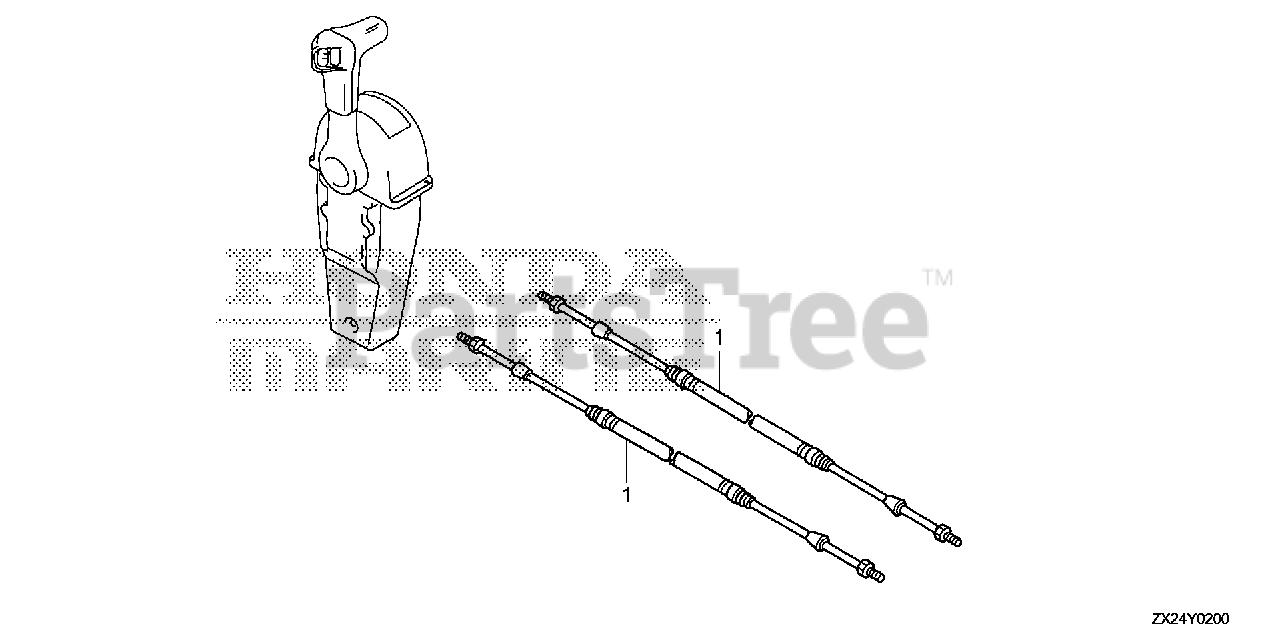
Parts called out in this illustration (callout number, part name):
1	CABLE, REMOTE CONTROL (10') (LOW FRICTION)
1	CABLE ASSY., PUSH-PULL (33C-5FT)
1	CABLE, REMOTE CONTROL (11') (LOW FRICTION)
1	CABLE ASSY., PUSH-PULL (33C-6FT)
1	CABLE, REMOTE CONTROL (12') (LOW FRICTION)
1	CABLE ASSY., PUSH-PULL (33C-7FT)
1	CABLE, REMOTE CONTROL (13') (LOW FRICTION)
1	CABLE ASSY., PUSH-PULL (33C-8FT)
1	CABLE, REMOTE CONTROL (14') (LOW FRICTION)
1	CABLE ASSY., PUSH-PULL (33C-9FT)
1	CABLE, REMOTE CONTROL (15') (LOW FRICTION)
1	CABLE ASSY., PUSH-PULL (33C-10FT)
1	CABLE, REMOTE CONTROL (16') (LOW FRICTION) (NOT AVAILABLE)
1	CABLE ASSY., PUSH-PULL (33C-11FT)
1	CABLE, REMOTE CONTROL (17') (LOW FRICTION)
1	CABLE ASSY., PUSH-PULL (33C-12FT)
1	CABLE, REMOTE CONTROL (18') (LOW FRICTION) (NOT AVAILABLE)
1	CABLE ASSY., PUSH-PULL (33C-13FT)
1	CABLE, REMOTE CONTROL (19') (LOW FRICTION)
1	CABLE ASSY., PUSH-PULL (33C-14FT)
1	CABLE, REMOTE CONTROL (20') (LOW FRICTION) (NOT AVAILABLE)
1	CABLE ASSY., PUSH-PULL (33C-15FT)
1	CABLE, REMOTE CONTROL (21') (LOW FRICTION)
1	CABLE ASSY., PUSH-PULL (33C-16FT)
1	CABLE, REMOTE CONTROL (22') (LOW FRICTION) (NOT AVAILABLE)
1	CABLE ASSY., PUSH-PULL (33C-17FT)
1	CABLE, REMOTE CONTROL (23') (LOW FRICTION)
1	CABLE ASSY., PUSH-PULL (33C-18FT)
1	CABLE, REMOTE CONTROL (24') (LOW FRICTION) (NOT AVAILABLE)
1	CABLE ASSY., PUSH-PULL (33C-19FT)
1	CABLE, REMOTE CONTROL (25') (LOW FRICTION)
1	CABLE ASSY., PUSH-PULL (33C-20FT)
1	CABLE, REMOTE CONTROL (26') (LOW FRICTION)
1	CABLE ASSY., PUSH-PULL (33C-21FT)
1	CABLE, REMOTE CONTROL (27') (LOW FRICTION)
1	CABLE ASSY., PUSH-PULL (33C-22FT)
1	CABLE, REMOTE CONTROL (28') (LOW FRICTION) (NOT AVAILABLE)
1	CABLE ASSY., PUSH-PULL (33C-23FT)
1	CABLE, REMOTE CONTROL (29') (LOW FRICTION)
1	CABLE ASSY., PUSH-PULL (33C-24FT)
1	CABLE, REMOTE CONTROL (30') (LOW FRICTION) (NOT AVAILABLE)
1	CABLE ASSY., PUSH-PULL (33C-25FT)
1	CABLE, REMOTE CONTROL (31') (LOW FRICTION)
1	CABLE ASSY., PUSH-PULL (33C-26FT)
1	CABLE, REMOTE CONTROL (32') (LOW FRICTION) (NOT AVAILABLE)
1	CABLE ASSY., PUSH-PULL (33C-27FT)
1	CABLE, REMOTE CONTROL (33') (LOW FRICTION)
1	CABLE ASSY., PUSH-PULL (33C-28FT)
1	CABLE, REMOTE CONTROL (34') (LOW FRICTION) (NOT AVAILABLE)
1	CABLE ASSY., PUSH-PULL (33C-29FT)
1	CABLE, REMOTE CONTROL (35') (LOW FRICTION)
1	CABLE ASSY., PUSH-PULL (33C-30FT)
1	CABLE ASSY., PUSH-PULL (33C-31FT)
1	CABLE ASSY., PUSH-PULL (33C-32FT)
